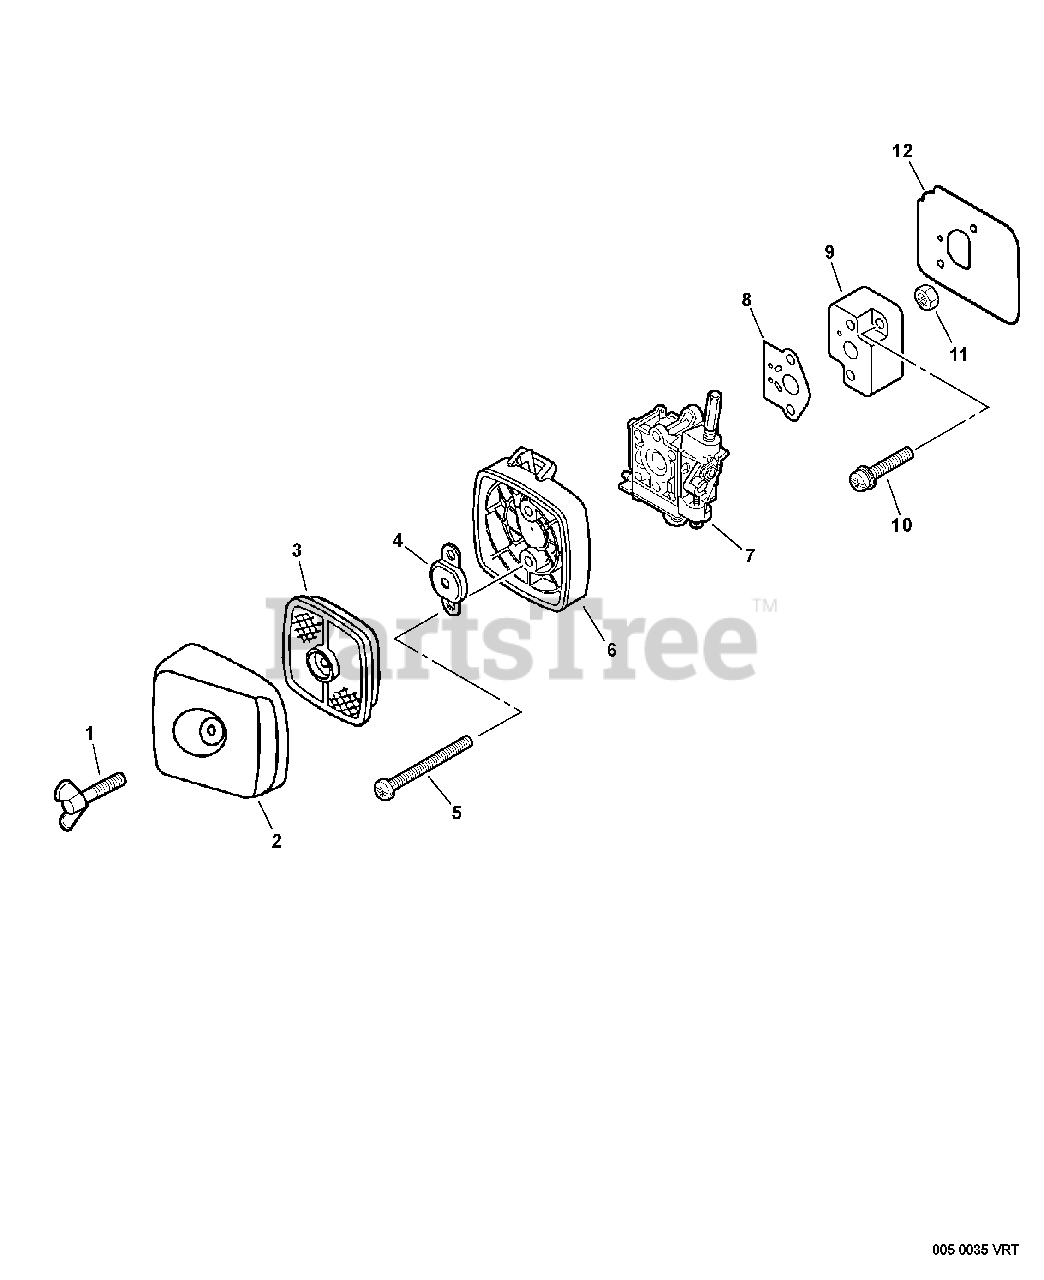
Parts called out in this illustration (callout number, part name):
1	BOLT, WING 5×20
2	COVER, AIR FILTER - GRAY
3	FILTER, AIR - SINGLE LAYER
4	PLATE, PREVENT
5	SCREW 5×65
6	CASE, AIR FILTER - GRAY
7	CARBURETOR
8	GASKET, CARBURETOR
9	INSULATOR, INTAKE
10	SCREW 5×20
11	NUT M5
12	HEAT SHIELD, INTAKE
